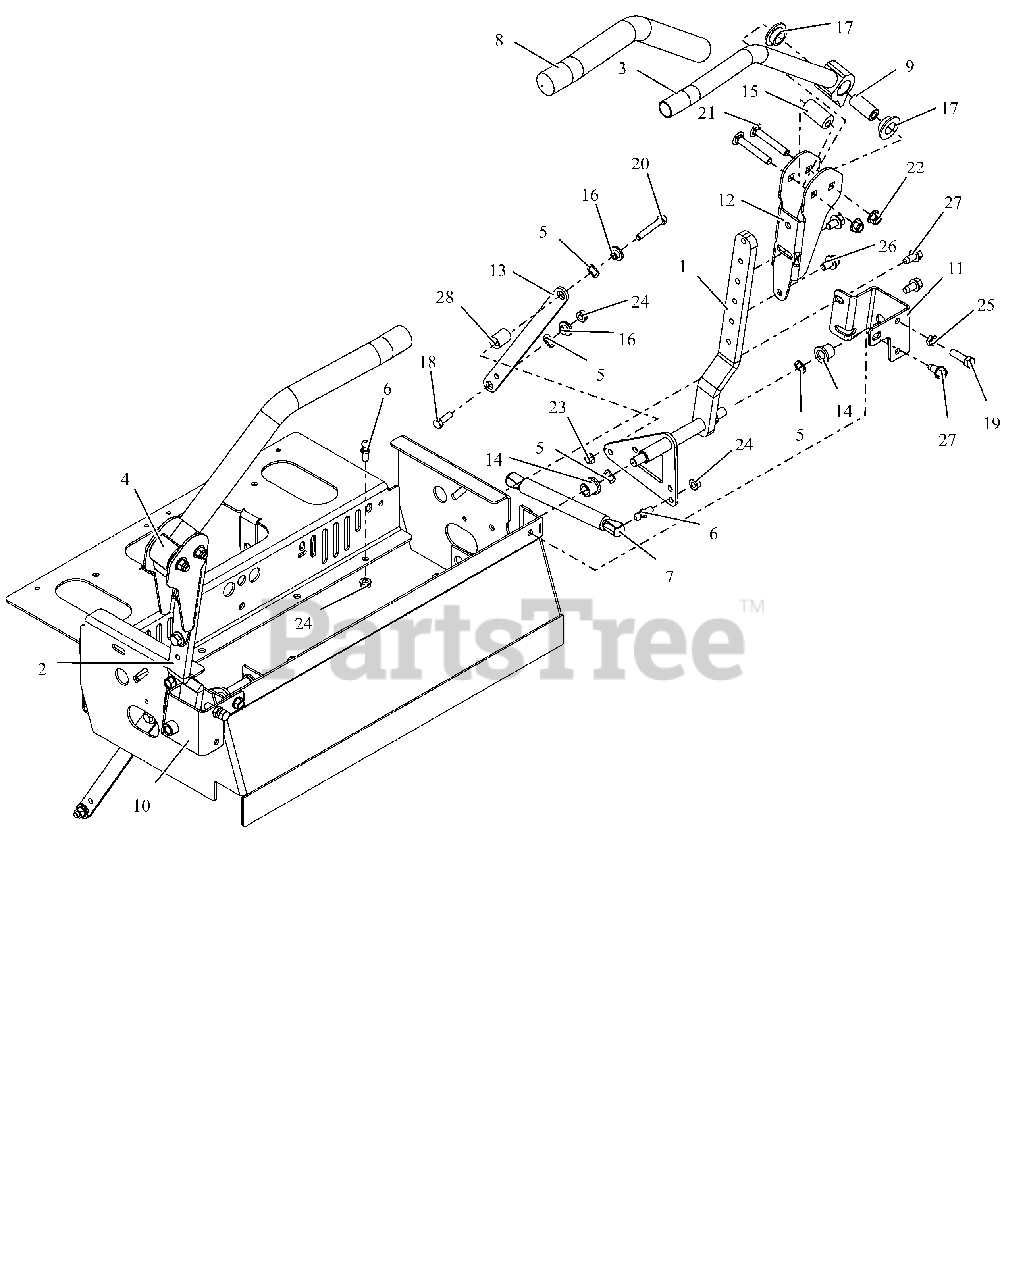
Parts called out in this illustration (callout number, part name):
1	WLDMT, LH LOWER CONTROL ARM
2	WLDMT, RH LOWER CONTROL ARM
3	WLDMT, CONTROL HANDLE-LH (BLACK)
4	WLDMT, CONTROL HANDLE-RH (BLACK)
5	WAVE WASHER .531X.781X.125FH
6	STUD- BALL
7	DAMPER
8	GRIP, HANDLEBAR
9	SPACER, STEERING ARM
10	PT200/400 RH CNTRL STP BRK-RED
11	PT200/400 LH CNTRL STP BRK-RED
12	ADJ UPPER CONTROL ARM BRKT-BLK
13	LINK, STEERING CONTROL
14	BHSG-FLG .500X.750X.750X.125
15	BSHG, ECCENTRIC.406X.875X1.625
16	BSHG-FLG .32X.500X.344X.880
17	BSHG-FLG .762X1.48X.44 NYL
18	BLT,HEX .31-18X1.00 G5 ZCC
19	BLT, HEX .38-16X1.25 G5 ZCC
20	BLT, HEX .31-18X2.00 G5 ZCC
21	BLT, RHSSN.38-16X2.50 G5 ZCC
22	NUT,NYL-FLG .38-16 GF ZCC
23	NUT,LK-CTR .31-18 GA ZCC
24	NUT-LK-TOP-FLG .312-18 GF ZCC
25	NUT-JAM .375-16 G2 ZCC
26	BLT, SERHFWH .38-16X.625 ZCC
27	SCR,TAP .375-16X.75 HWH TR ZCC
28	ECCENTRIC
